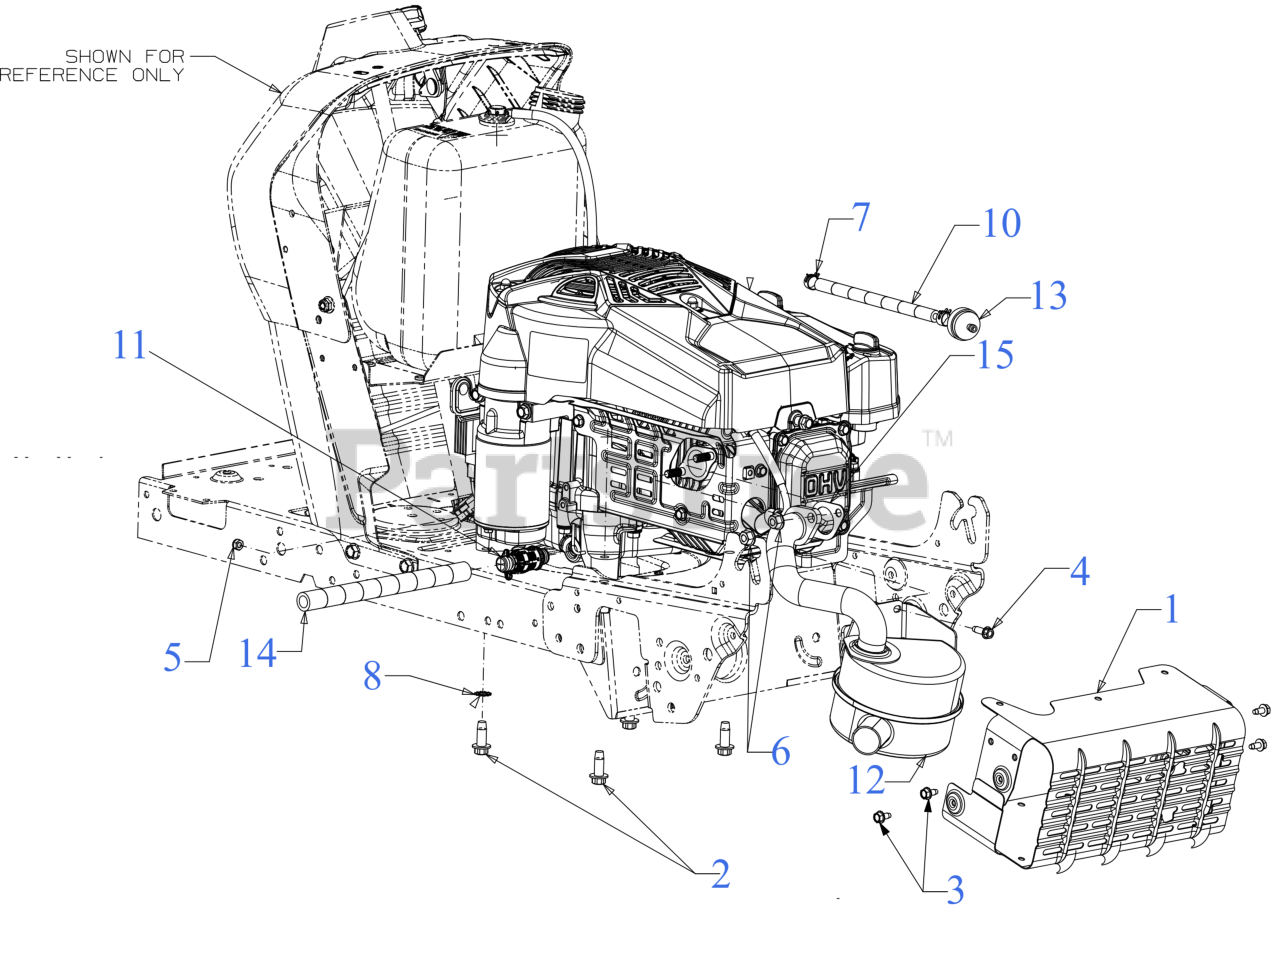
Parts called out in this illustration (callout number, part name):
1	MUFFLER SHIELD
2	SCREW 3/8-16 x 1
3	SCREW 1/4-20 X.500
4	SCREW 1/4-20 x .750
5	HEX NUT
6	HEX FLANGE NUT M8X
7	HOSE CLAMP 1/20
8	LOCK WASHER 3/8
10	FUEL HOSE LOW PERMEATION 13"
11	OIL DRAIN VALVE
12	EXHAUST MUFFLER (ZS)
13	FUEL FILTER
13	Genuine Factory Parts FUEL FILTER
14	DRAIN HOSE 14''
15	EXHAUST GASKET
